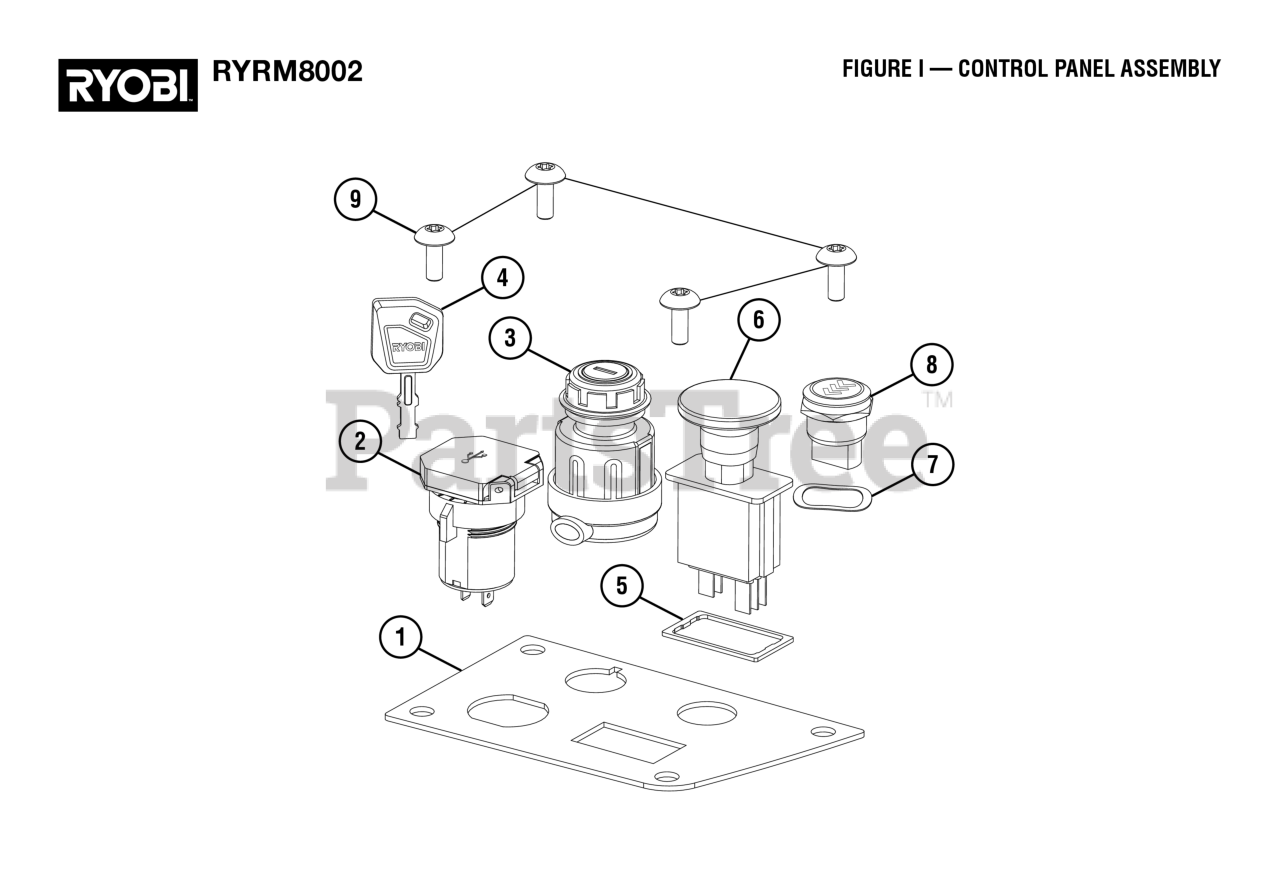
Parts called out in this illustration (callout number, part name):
1	Control Panel Plate
2	USB Module
3	Key Module
5	PTO Gasket
6	Power Take Off (PTO) Button
7	Wavy Washer
8	Accessory Button
9	Screw (M6 x 10 mm, Soc. Button Hd.)
